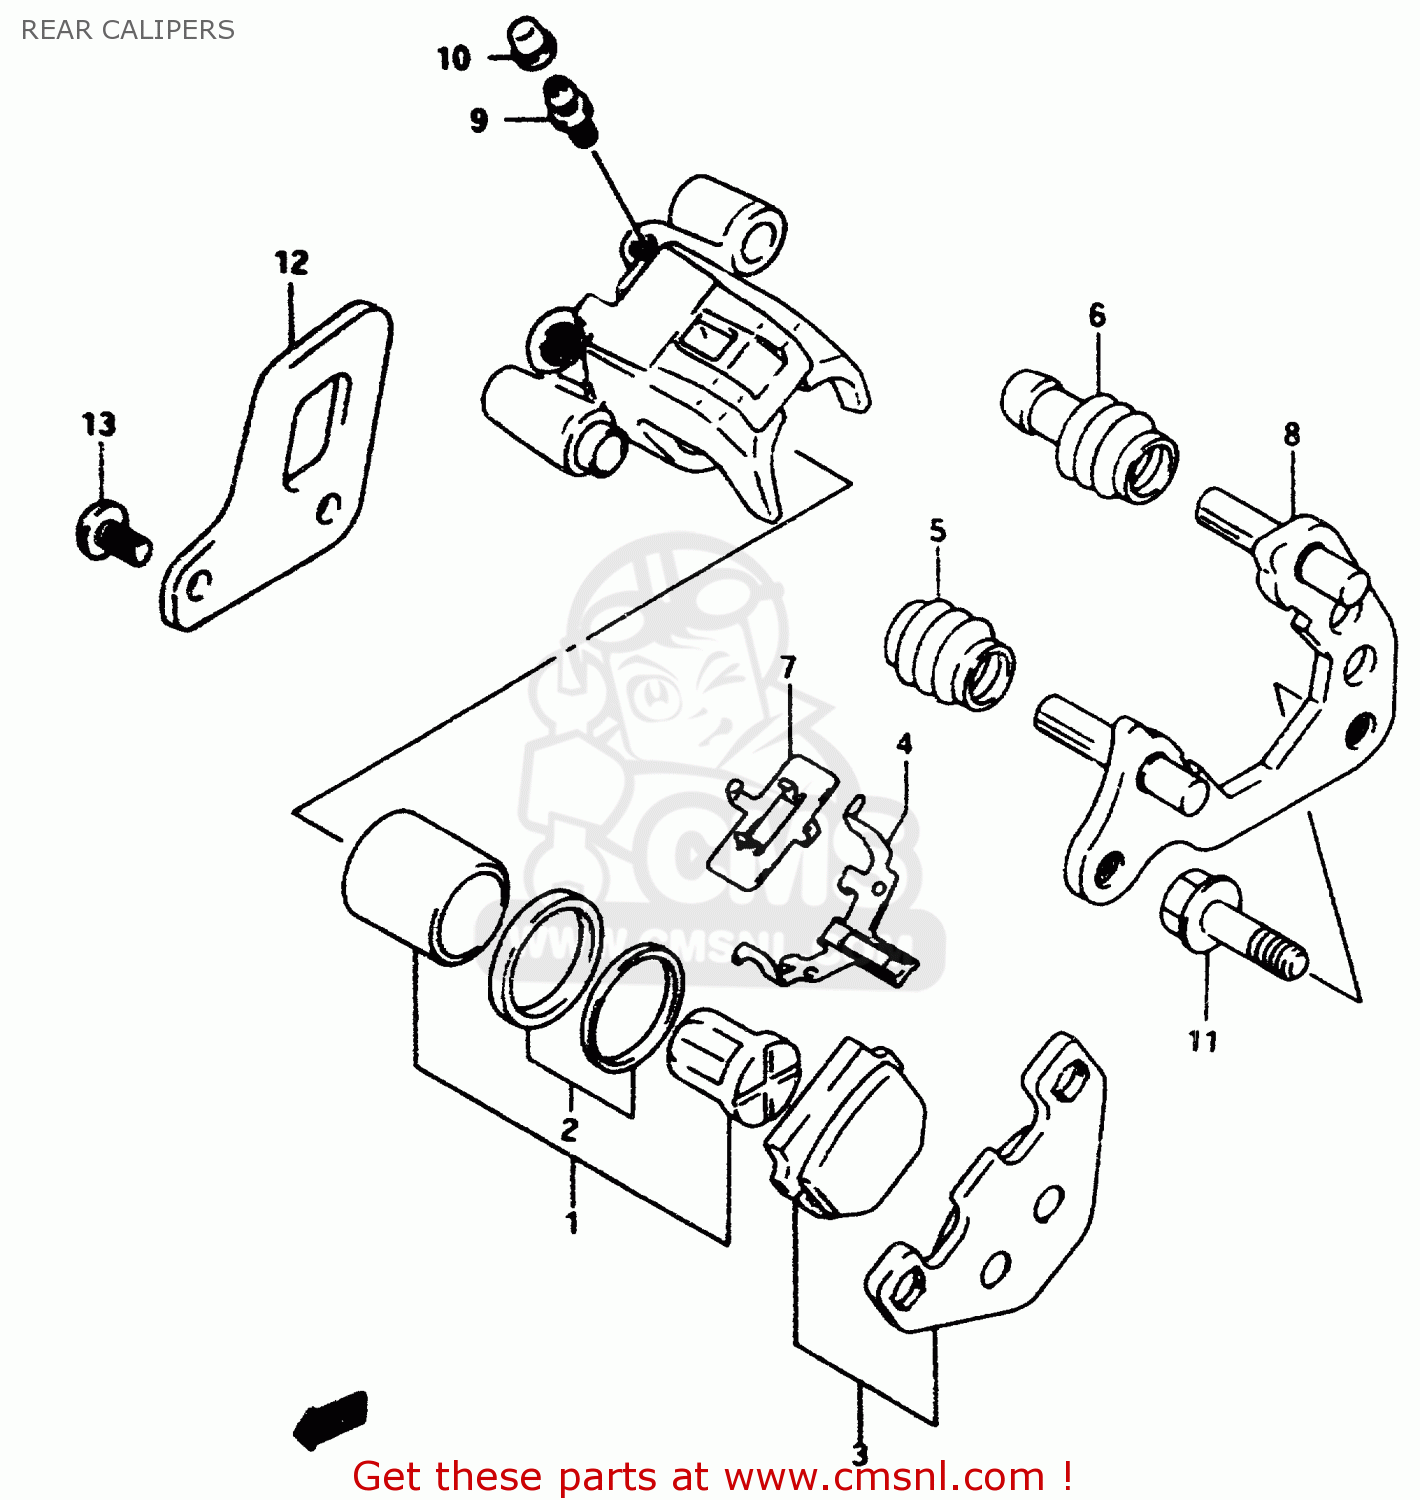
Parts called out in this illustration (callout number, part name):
1	PISTON SET
2	SEAL SET,PISTON
3	PAD SET (NAS)
4	SPRING,PAD
5	BOOT,AXLE
6	INSULATOR,AXLE
7	SHIM
8	CARRIER,CALIPER
9	BLEEDER
10	CAP,BLEEDER PLUG
11	BOLT(8X18)
12	GUARD,RR CALIPER
13	SCREW(6X12)
